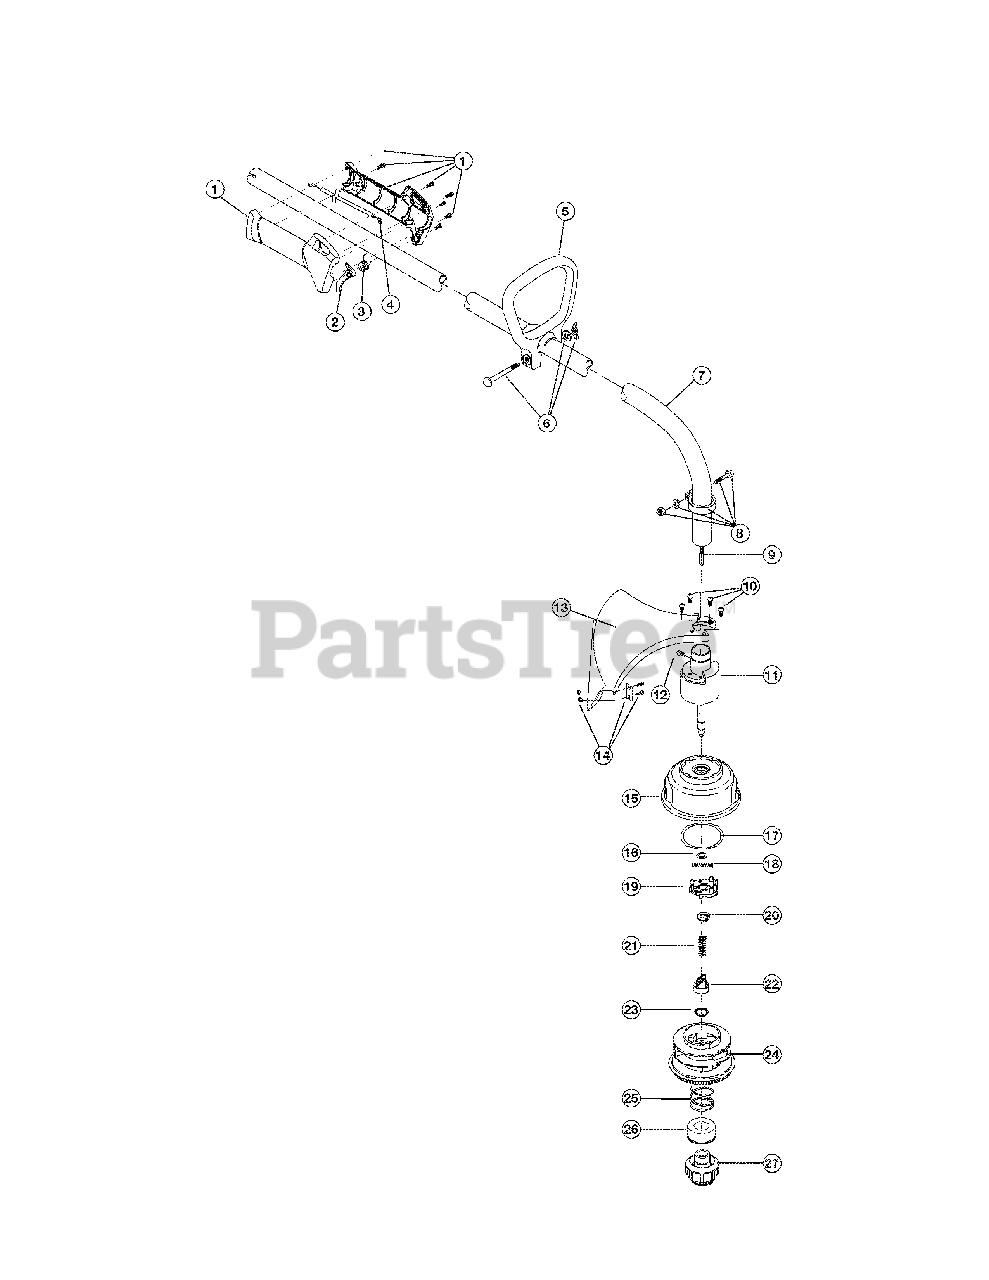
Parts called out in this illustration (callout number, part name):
1	Throttle Housing Assembly (includes 2 & 3)
2	Throttle Trigger Spring
3	Throttle Trigger
4	Throttle Cable Assembly
5	D-Handle Assembly (includes 6)
6	D-Handle Hardware
7	Drive Shaft Housing Assembly (includes 9)
8	Lower Clamp Assembly
9	Flexible Drive Shaft
10	Shield Mounting Screw
11	Bushing Housing Assembly
12	Anti-Rotation Screw
13	Shield Assembly (includes 14)
14	Blade Assembly
15	Outer Spool Assembly (includes 16)
16	Retainer
17	Thrust Washer
18	Small Spring
19	Slider
22	Plunger
24	Inner Reel
25	Large Spring
26	Foam Seal
27	Bump Head Knob Assembly (includes 25 & 26)
